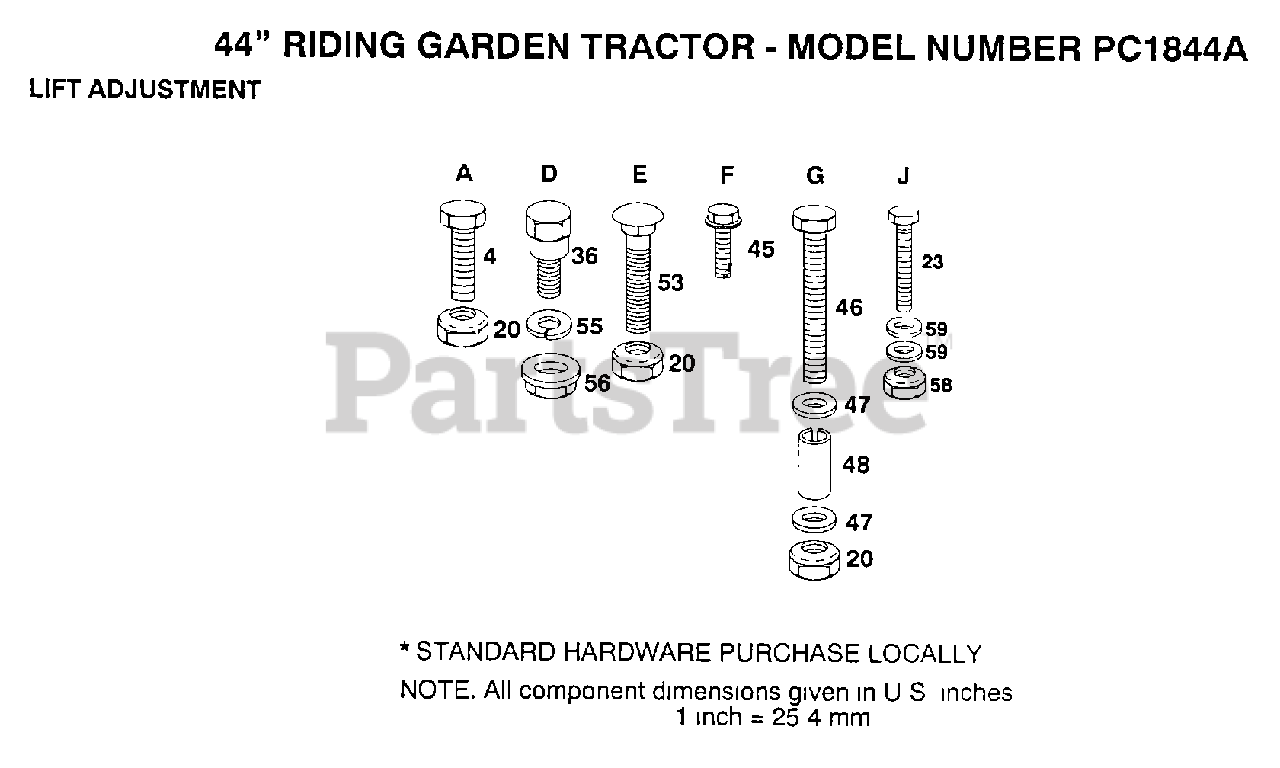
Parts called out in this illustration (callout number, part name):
23	BOLT LT
36	"BOLT, SHOULDER LT"
45	SCREW
55	WASHER T
56	NUT SPECIAL T
59	WASHER
